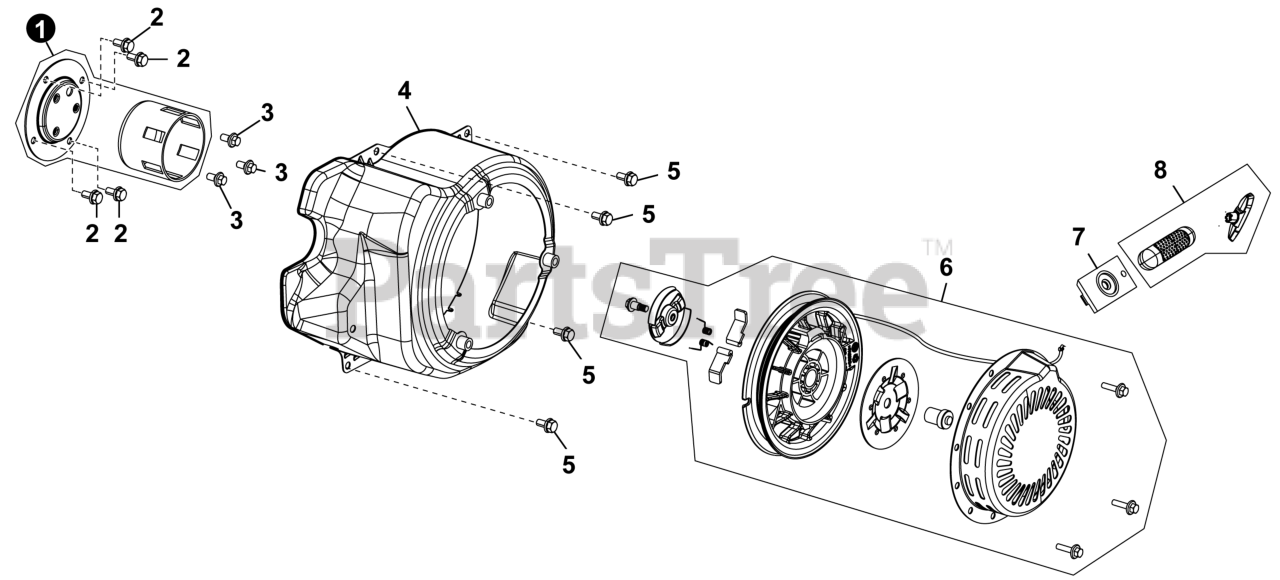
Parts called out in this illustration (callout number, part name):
1	ASSY., STARTER CUP
4	SHROUD, FAN
6	ASSY., STARTER RECOIL
7	GUIDE, STARTING ROPE
8	HANDLE, STARTER ROPE
